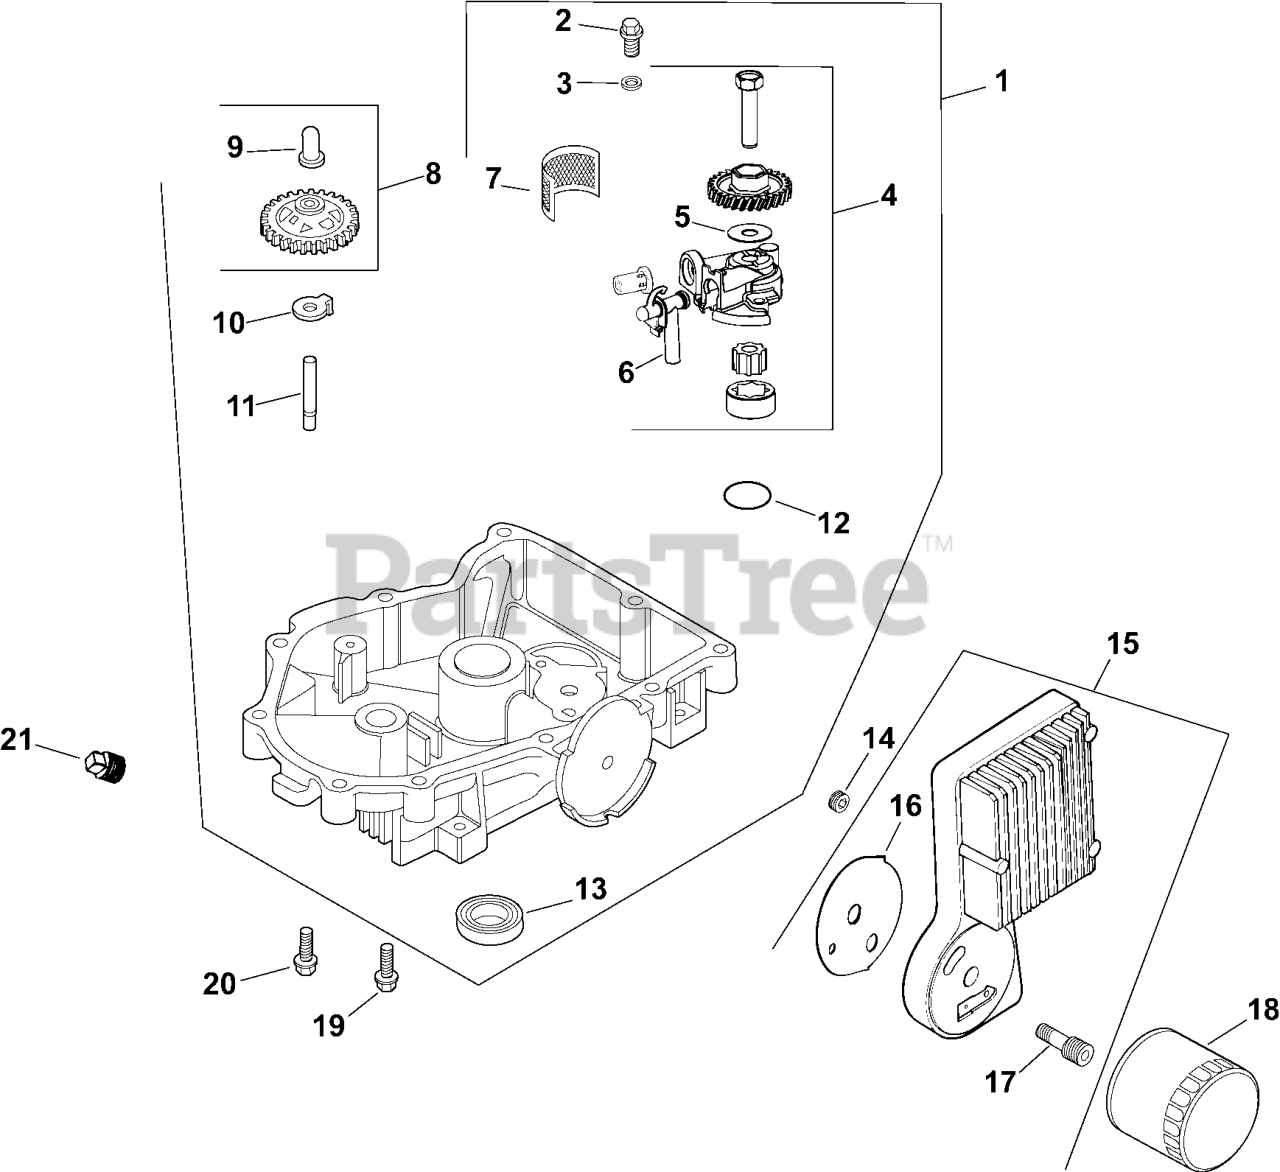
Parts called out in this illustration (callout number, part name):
1	PAN , OIL ASSEMBLY USE 24 199 32-S
2	SCREW,FLG THD FRM M6X1.0X25-(#25086395S)
3	WASHER, FLAT 6 MM
4	PUMP, OIL-DISCONTINUED
4	OIL PUMP ASSY KIT-USE 24 393 53-S
5	O-RING, OIL PICK-UP
6	KIT, OIL PICK-UP TUBE-(#DSC)
7	SCREEN, OIL
8	KIT, GOVERNOR GEAR W/PIN
9	PIN, GOVERNOR REGULATING
11	SHAFT, GOVERNOR GEAR
13	SEAL, OIL (KM)-USE 25 032 06-S
14	PLUG, PIPE CTSK 3/8"
15	KIT, OIL COOLER
16	GASKET, OIL FILTER ADAPTER USE 24 041 88-S
17	NIPPLE, OIL FILTER
18	OIL FILTER
19	SCREW, HEX FLANGE -USE 24 086 17-S
20	SCREW, FLG M8X1.25X45
21	PLUG, SQ HD PIPE 3/8"
